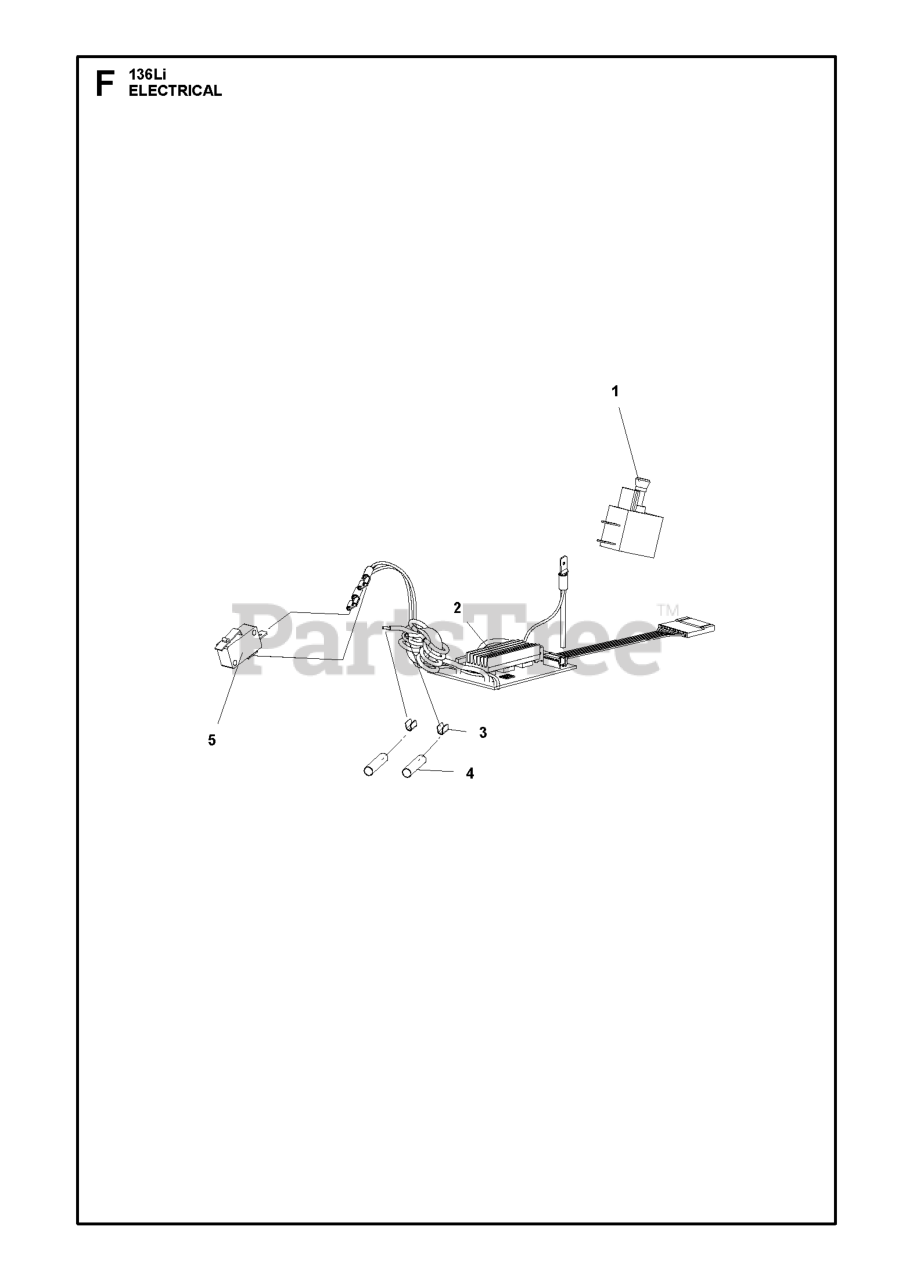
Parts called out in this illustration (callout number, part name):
1	MAIN SWITCH
2	CONTROL UNIT PCBA
5	MICRO SWITCH
